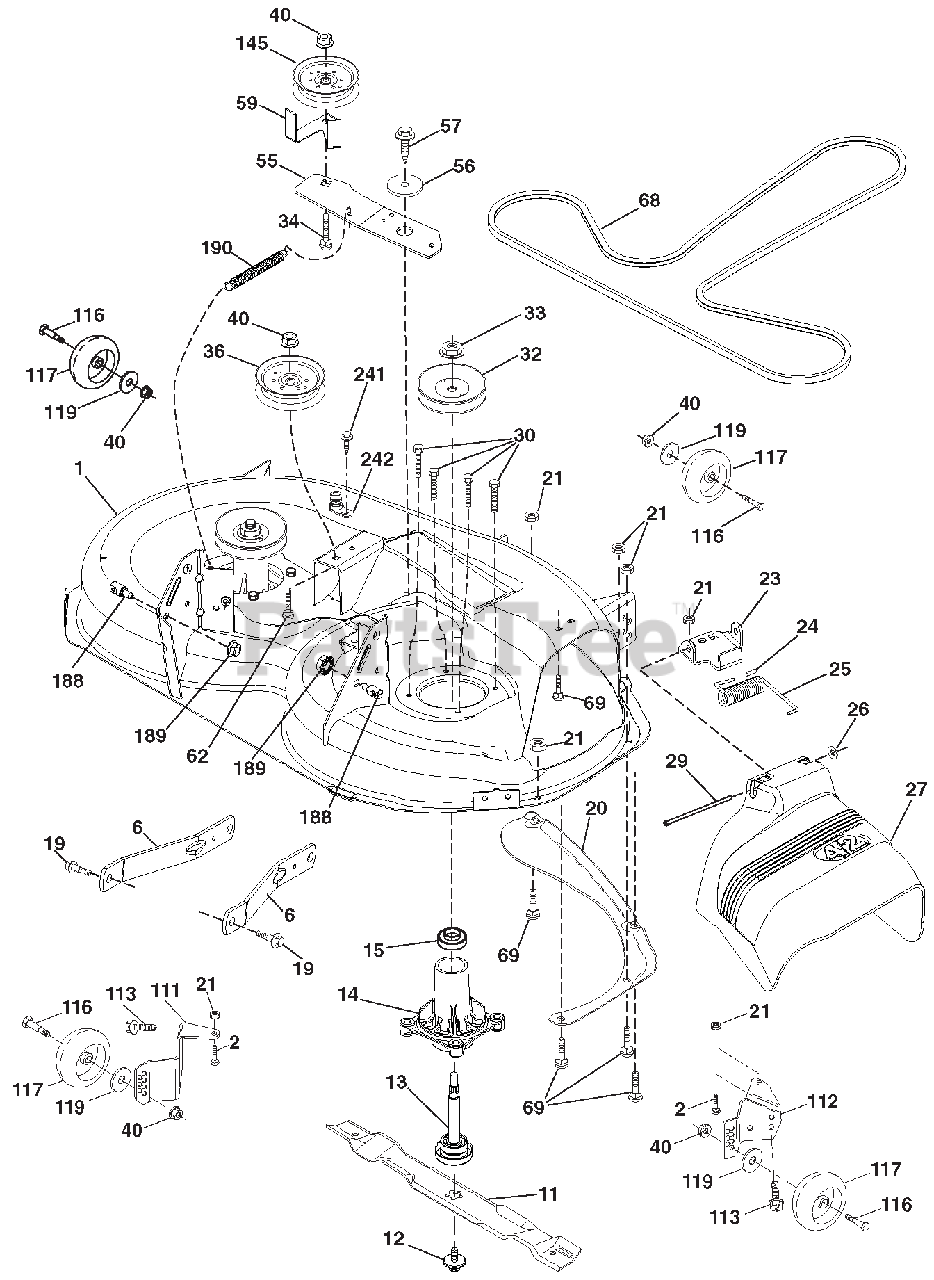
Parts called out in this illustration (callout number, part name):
1	MOWER HOUSING
6	ARM.SUSPENSION.MOWER.REAR.LD
11	BLADE.MOWER.42"HI LIFT PREMIUM
12	SCREW 7/16-20 X 1
13	SHAFT ASM
14	HOUSING.MANDREL.4PT.SERVICE
15	BEARING
19	BOLT.SHOULDER
20	BAFFLE.VORTEX.42.STD/HEAVY DTY
21	Nut, Hex, Crownlock 5/16-18
23	BRACKET.DEFLECTOR.38/42"2005
24	CAP.SLEEVE..80X.112.BLK.MOWER
25	SPRING.TORSION.DFL.38/42/46.GR
26	NUT.PUSH.PHOS.& OIL
27	SHIELD.DEFLECTOR.
29	ROD.HINGE.42/46"
30	SCREW.THD ROLL.DOD PT.HEX
32	MANDREL.PULLEYS.42,44,50
32	MANDREL ASM
33	NUT.FLANGE.LOCK.TOP
34	BOLT.CARR.SH.3/8-16X1-1/2.GR5
36	PULLEY.IDLER.4.50.RAW
40	Nut, Hex, Flangelock 3/8-16
55	IDLER.ARM
56	SPACER.RETAINER
57	SCREW.3/8-16X1.SMGML.TAP/R.BLK
59	GUARD.TUV.IDLER
62	BOLT.RD.HD.SQ.NK.3/8-16UNC X 2
68	V-Belt, 42" Mower
69	BOLT.RDHD.SQNK.5/16-18 X 5/8
111	BRACKET WHEEL GAUGE LH
112	BRACKET WHEEL GAUGE RH
113	BOLT.5/16-18HEX.WHS.HD.LCKSERR
116	BOLD SHLD "A" 2.41 "B" 1.66
117	WHEEL.GAGE.HALF.SPOKED
119	Washer 3/8 x 7/8 x 14 Ga.
145	PULLEY.IDLER 48"PRIMARY
188	STUD.FASTNER.W/'D'ANTI-ROTATIO
189	Nut, Lock Hex Flange 5/16-18 u
242	PORT WASHOUT
